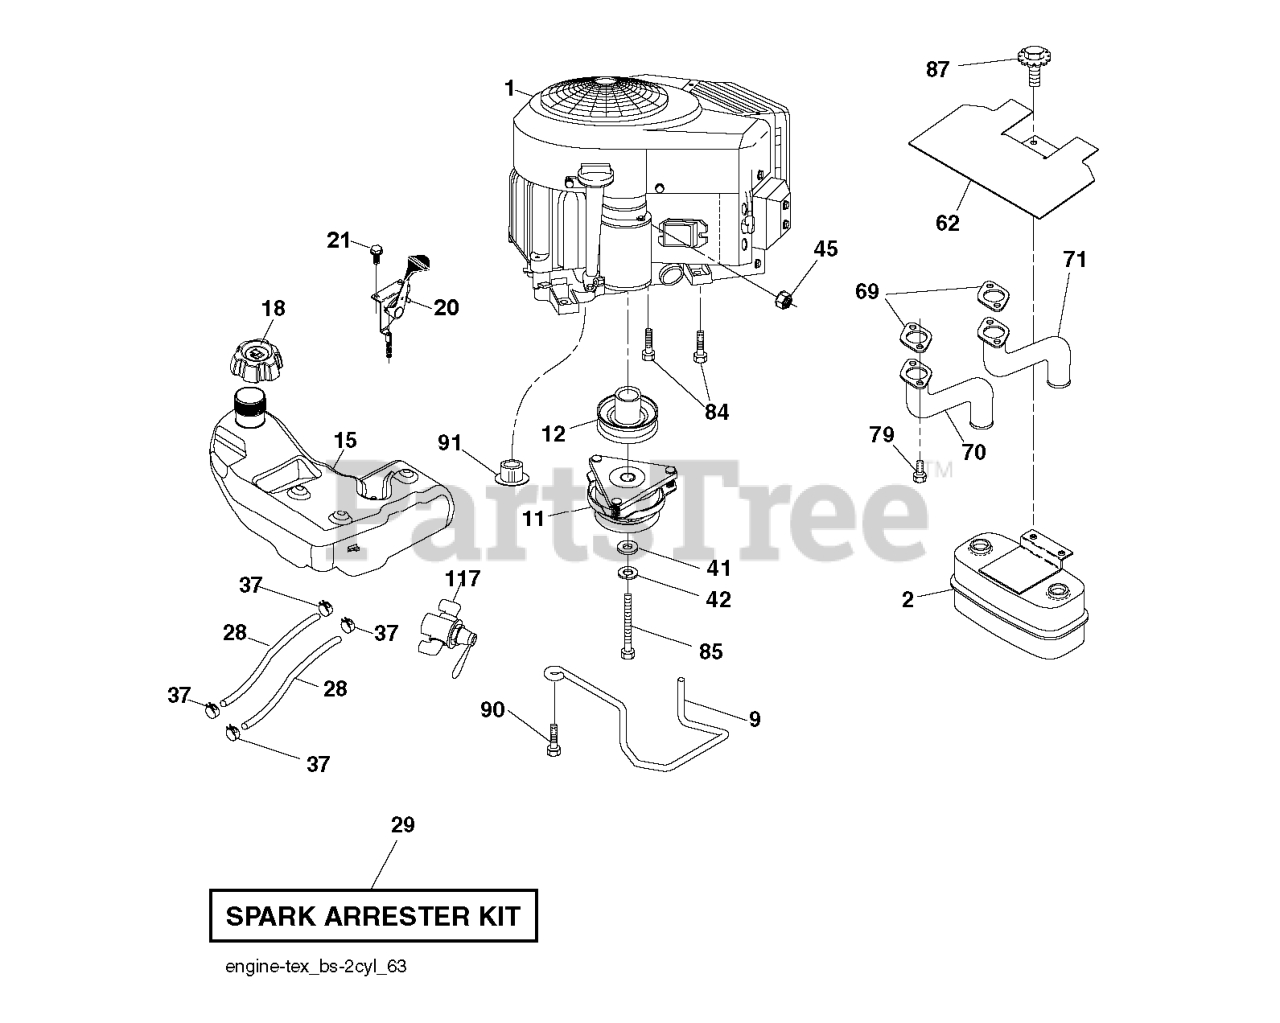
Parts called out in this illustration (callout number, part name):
2	MUFFLER.TWIN.CYL.LOW.TONE
9	KEEPER BELT ENGINE
11	CLUTCH MZ ZTR GT.48/54"1.125"
12	PULLEY ENGINE
18	RP CAP FUEL
20	THROTTLE CABLE
21	SCREW.#10 X 0.750.BOS
28	REPL BY 532 00 85-43
29	KIT.SPARK ARRESTOR 794945 B&S
37	HOSE CLAMP
42	LOCKWASHER
45	NUT
62	RP SHIELD HEAT MUFFLER
69	GASKET.MUFFLER
70	RP.EXHAUST.TUBE.LH.BS/TWIN
71	EXHAUST.TUBE.RH.BS/TWIN
79	SCREW.SOCKET.HEAD.5/16-18
84	SCREW.3/8-16
85	BOLT HEX 7/16-20 X 3.75 GR. 5
87	BOLT.5/16-18UNCX1.W/SEMS.BLK
90	SCREW 3/8-16X1
91	BUSHING.1.375OD
117	VALVE FUEL RESERVE
